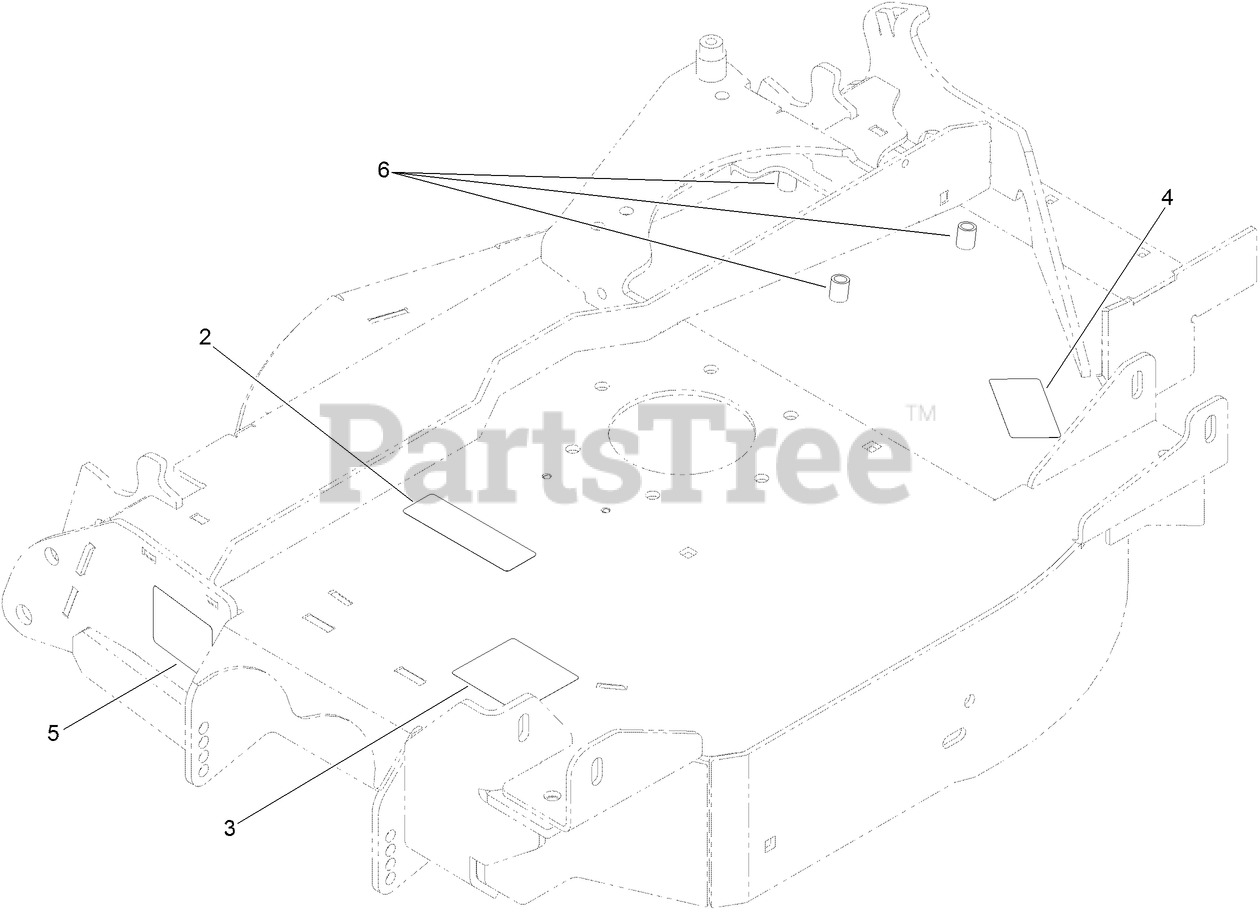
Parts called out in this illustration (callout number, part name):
2	DECAL-COVER, MISSING
3	DECAL-DANGER, THROWN OBJECT
4	DECAL-BOLT TORQUE
5	DECAL-WARNING, PINCH POINT
6	NUT-CLINCH
